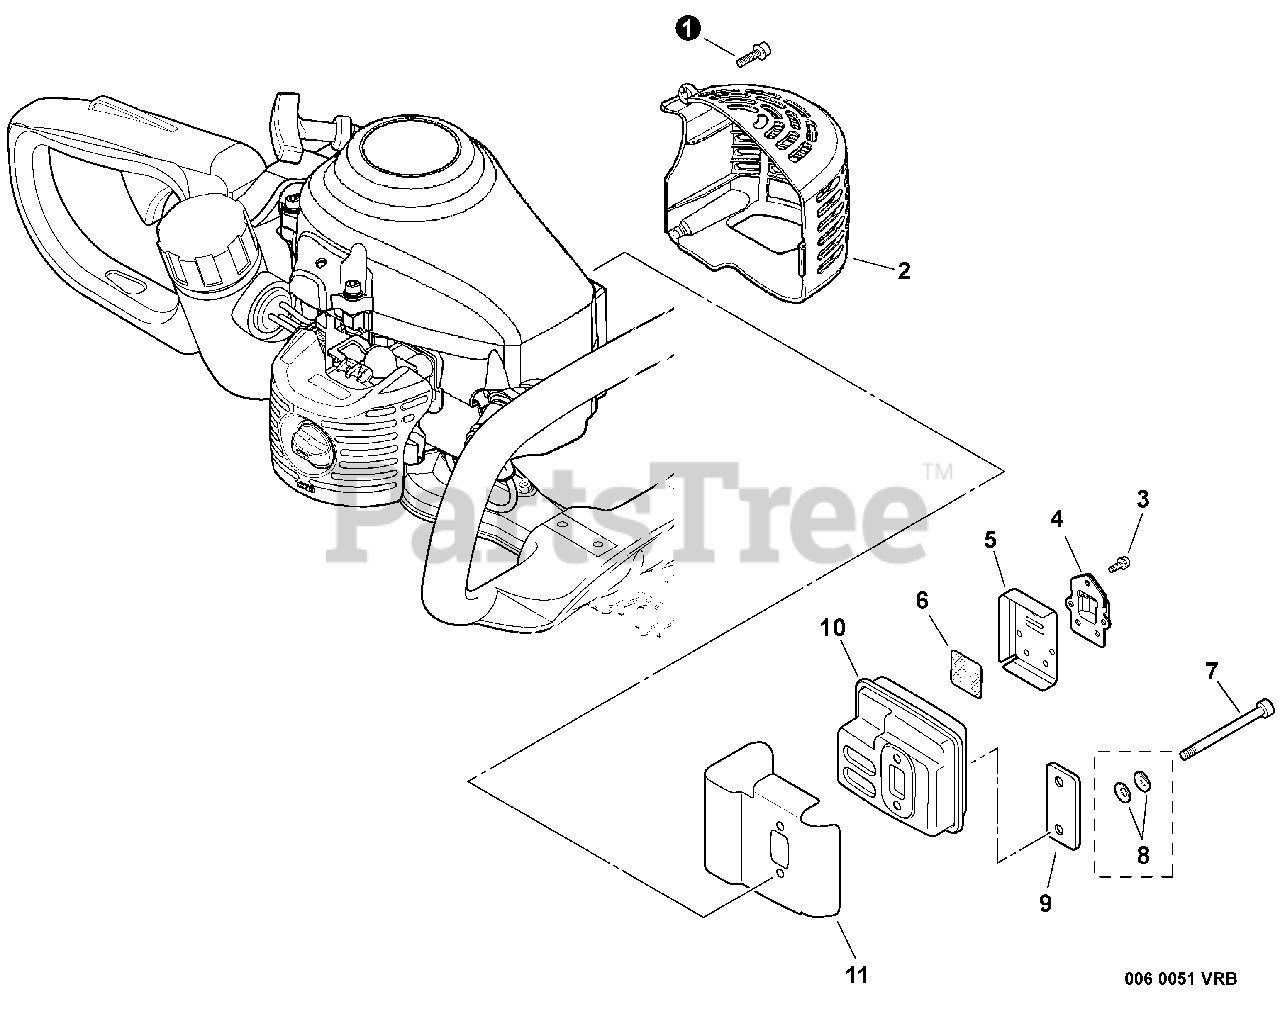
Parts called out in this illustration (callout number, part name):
1	SCREW - 5X16
2	COVER, EXHAUST
3	SCREW - 4X10
4	GUIDE, EXHAUST
5	GASKET, EXHAUST
6	SCREEN, SPARK ARRESTOR
7	SCREW - 5X55
8	WASHER - CONICAL
10	MUFFLER
11	SHIELD, EXHAUST
